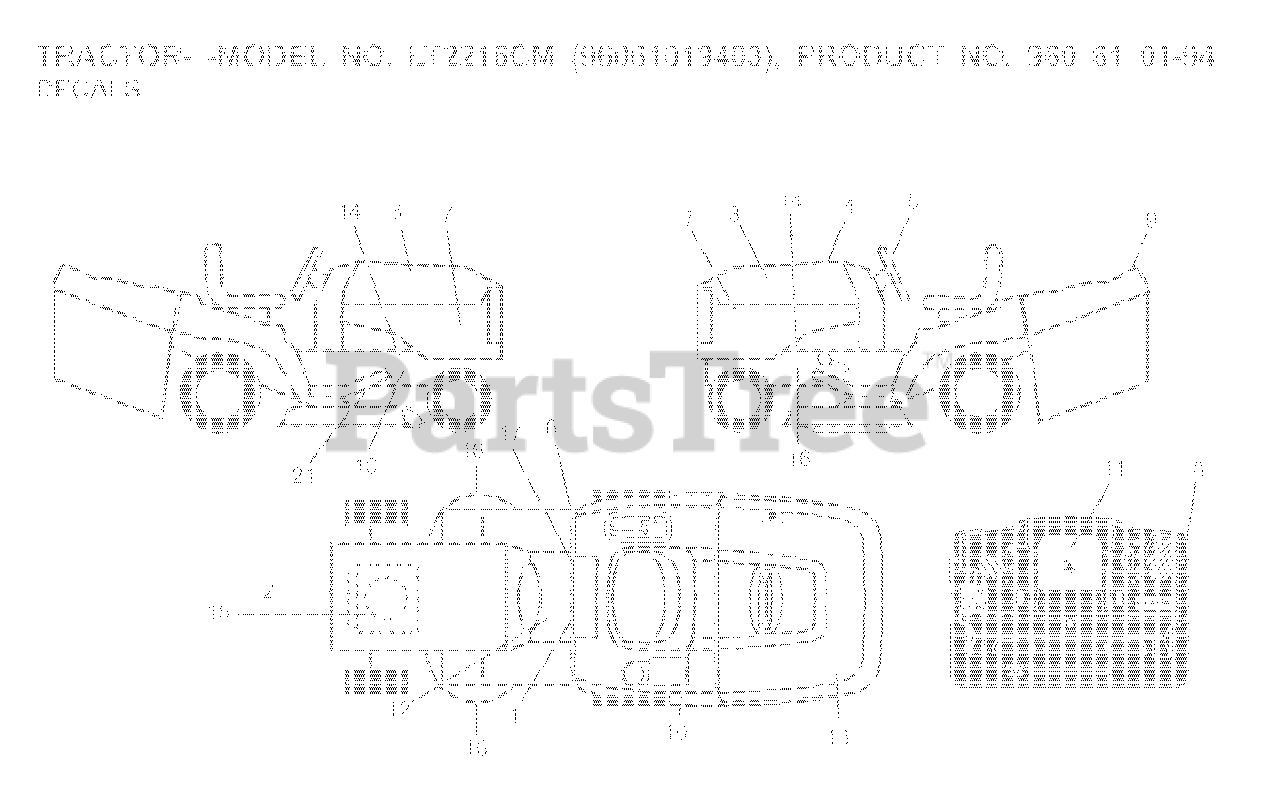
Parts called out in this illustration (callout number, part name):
8	KNOB.SKID.PLATE
10	DECAL BTRY SYMBOLS
11	DECAL.INTERNATIONL.CUTFINGER
17	DECAL PARK BRAKE
